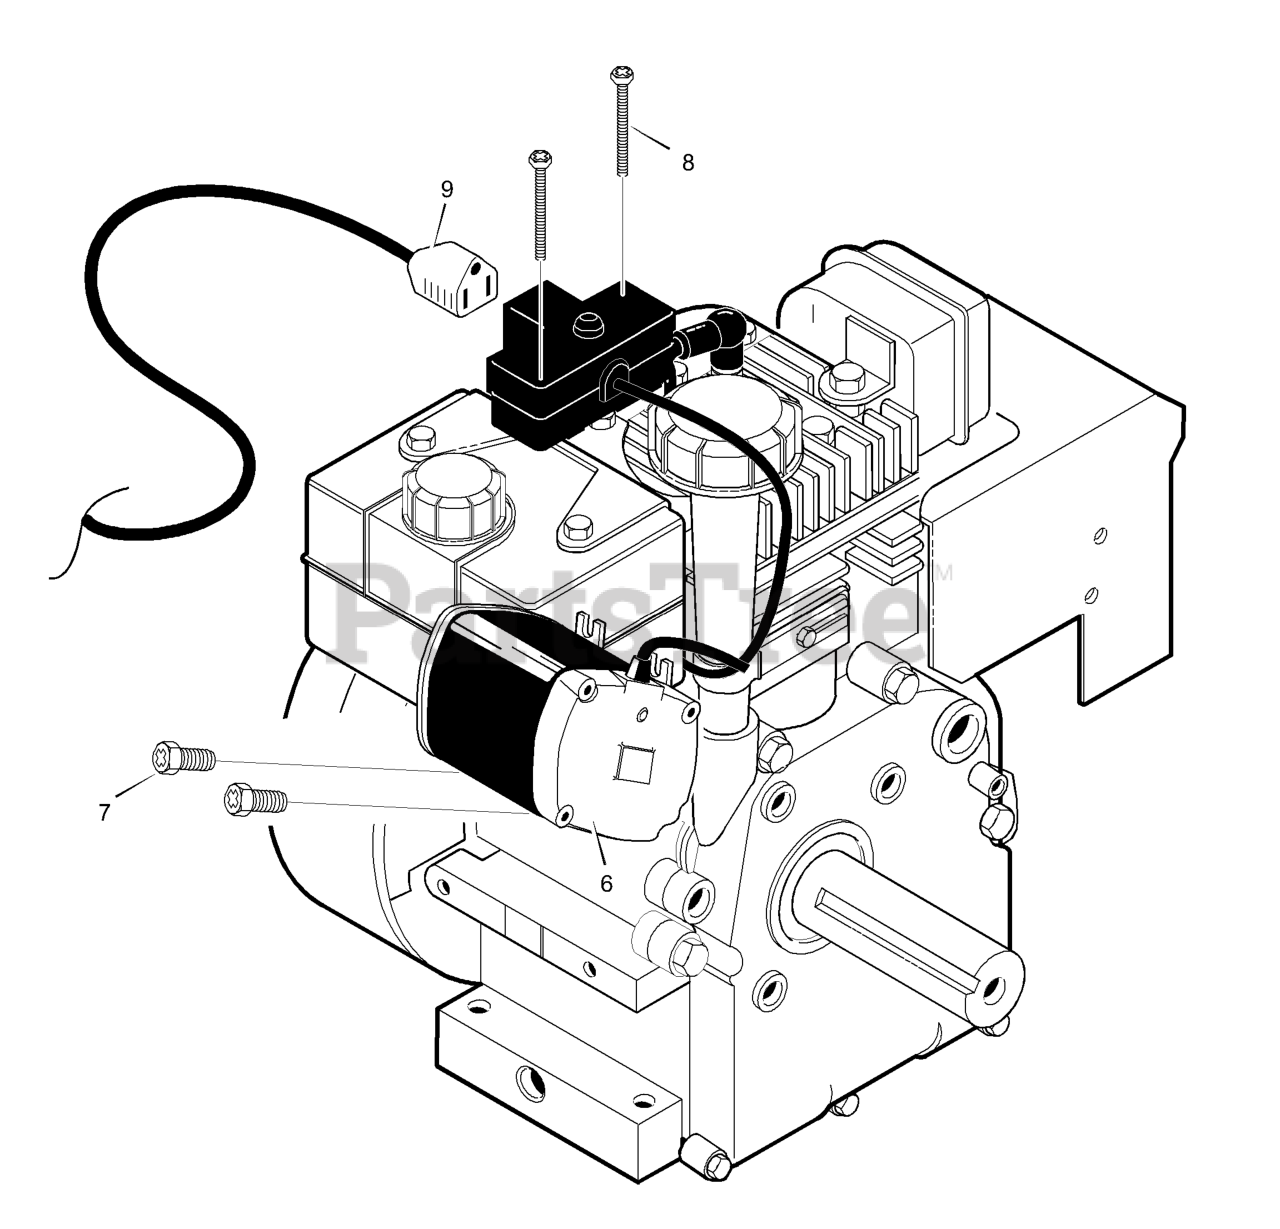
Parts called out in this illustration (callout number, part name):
6	MOTOR, STARTER
8	SCREW
9	CORD, Electric, 10FT. 110V
